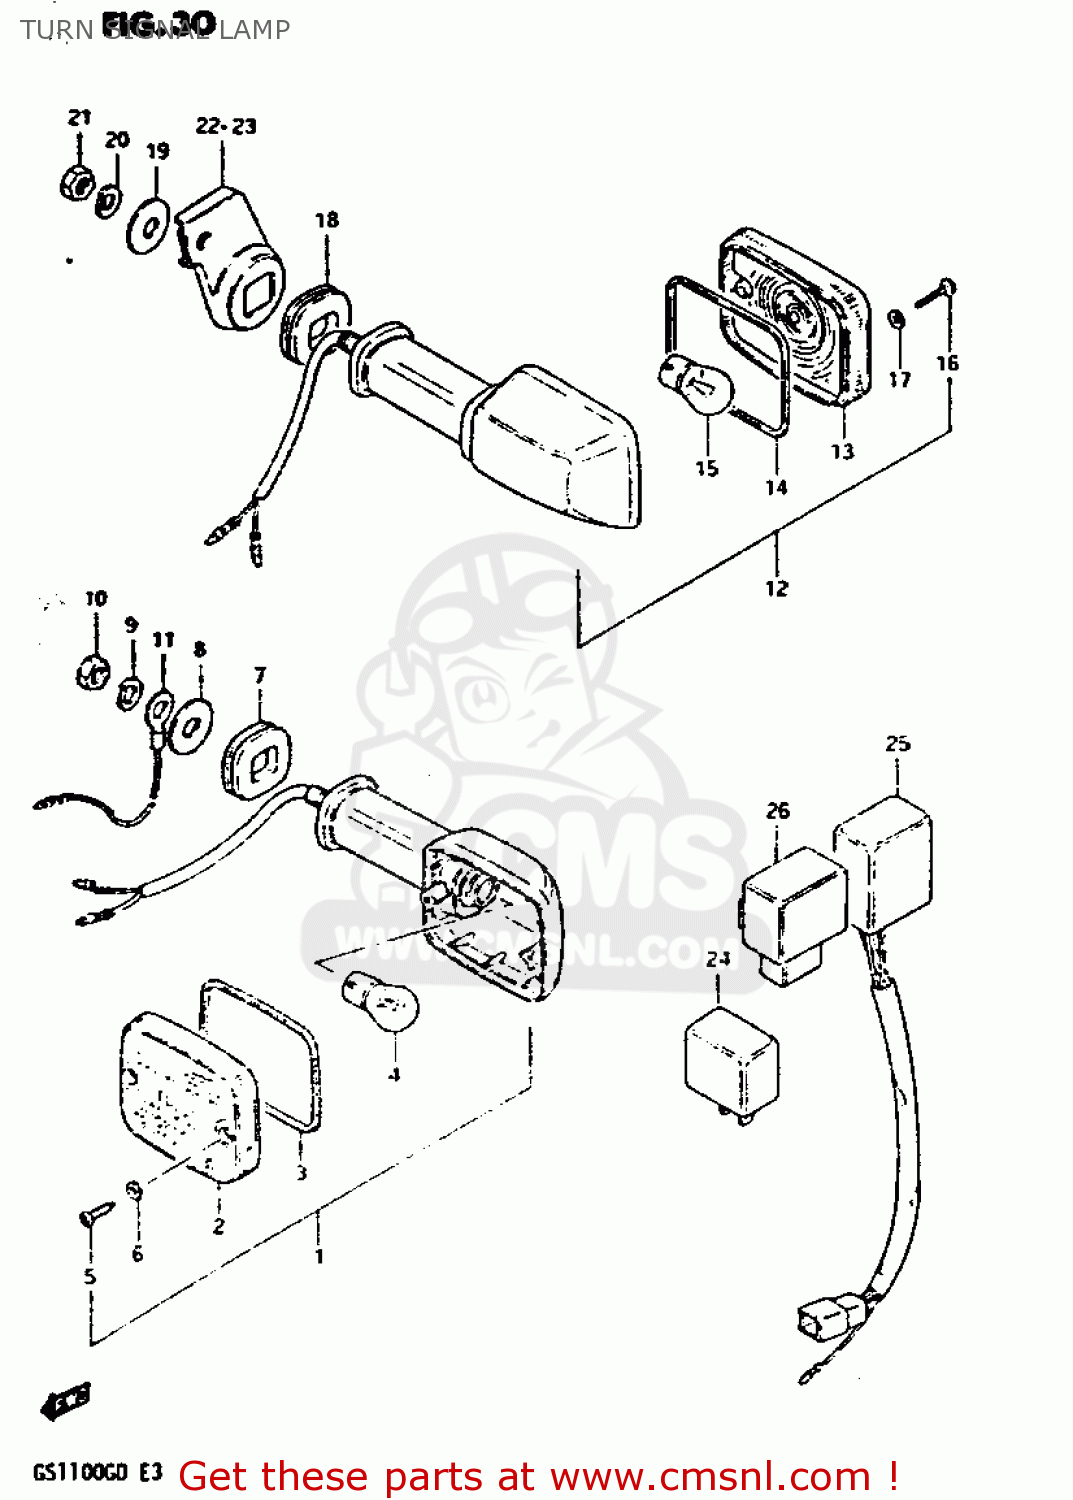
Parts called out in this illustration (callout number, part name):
1	LAMP ASSY,FR TURN SIGNAL
2	LENS
3	GASKET (NAS)
4	BULB(12V23W)
5	SCREW
6	GASKET (NAS)
7	CUSHION
8	WASHER (10.5X30X2.3)
9	WASHER,LOCK,10
10	NUT
11	WIRE
12	LAMP ASSEMBLY,FRONT TURN SIGNAL
13	LENS
14	GASKET (NAS)
15	BULB(12V23W,STANLEY,A4577A)
16	SCREW
17	GASKET (NAS)
18	CUSHION
19	WASHER (10.5X30X2.3)
20	WASHER,LOCK,10
21	NUT
22	BRACKET,REAR TURN SIGNAL
23	BRACKET,REAR TURN SIGNAL
24	RELAY ASSY,TURNSIGNAL
25	UNIT,TURN SIGNAL CONTROL
26	UNIT,TURN SIGNAL CONTROL
